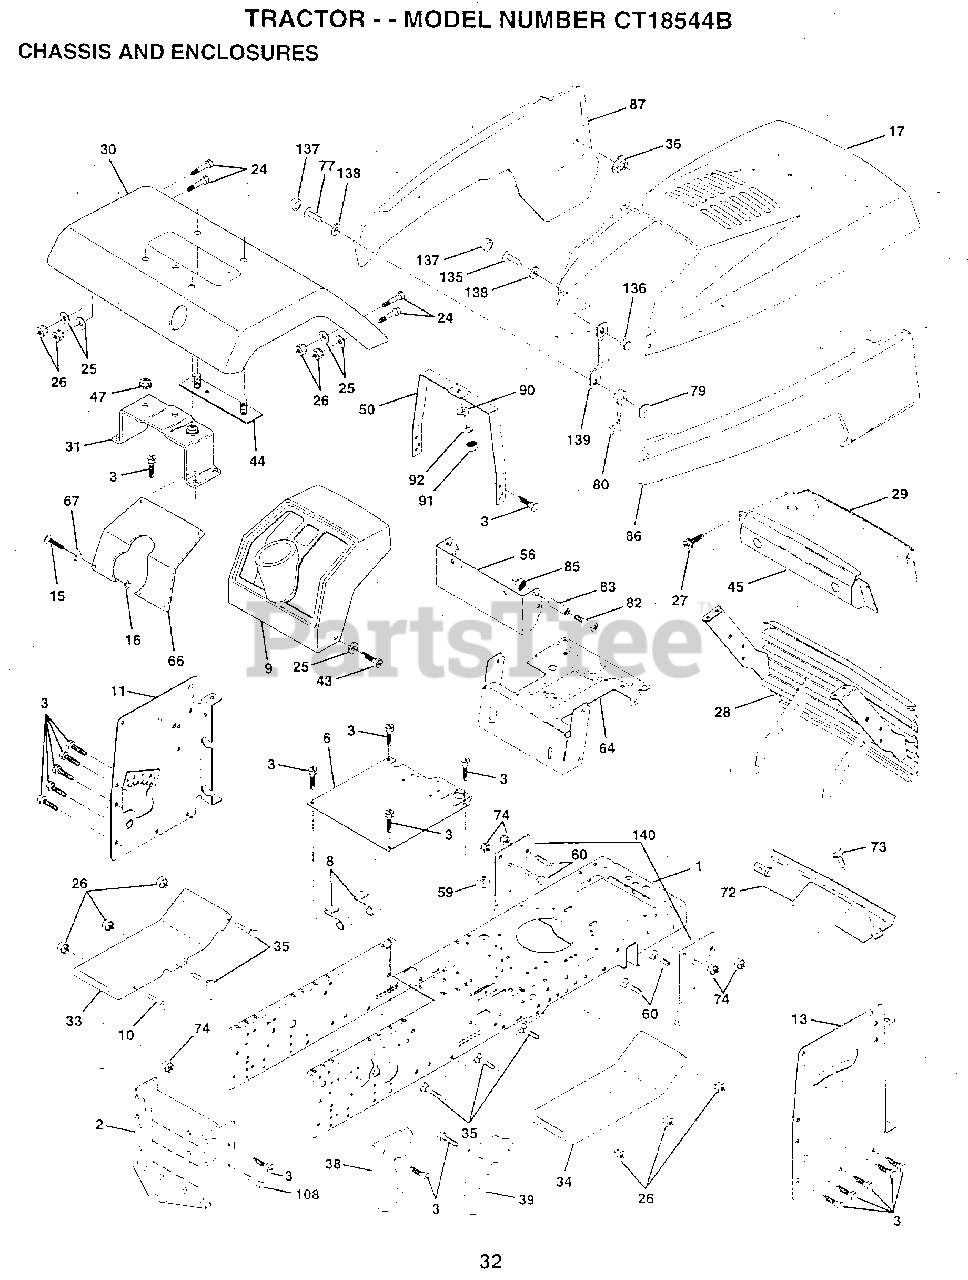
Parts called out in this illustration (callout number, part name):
1	CHASSIS WLDMT 11G
3	SCREW
8	"CLIP,INSULATOR"
9	DASHBOARD BLACK
11	PANEL.DASH.LH.PNT
13	PANEL.DASH.RH.PNT
15	SCREW
17	HOOD PNT YARDPRO
24	BOLT
25	WASHER
26	NUT
28	GRILLE ASM PNT
29	LENS.BAR.CLEAR
30	FENDER PNT
31	BRKT.ASM.FENDER
33	FOOTREST.LH.LT/GT
34	FOOTREST.RH.LT/GT
35	BOLT
36	PAL NUT LT
38	BRACKET ASM LH
39	BRACKET ASM RH
43	SCREW
44	STRAP ASM FENDER
45	BEZEL.ASM.
47	NUT-PUSH YT
50	DASH.SUPT.YP/HUSQ
56	EXT DASH LTYT
60	BOLT
64	DASH.LOWER.LT
66	PLATE SLKSCR YP
67	WASHER
72	STRAP.PNT.GRILLE
73	SCREW CRT
77	SCREW
79	WELDNUT
80	HOOD LATCH T
82	SCREW
83	SPACER LT
86	PANEL PNT RH SIDE
87	PANEL PNT LH SIDE
90	WASHER PM
92	LOCKWASHER
135	SCREW.10-24X3/8.
136	ACORN NUT RB
137	SNAP CAP LT
138	WASHER LT
139	BKT.SPT.HOOD/PANL
